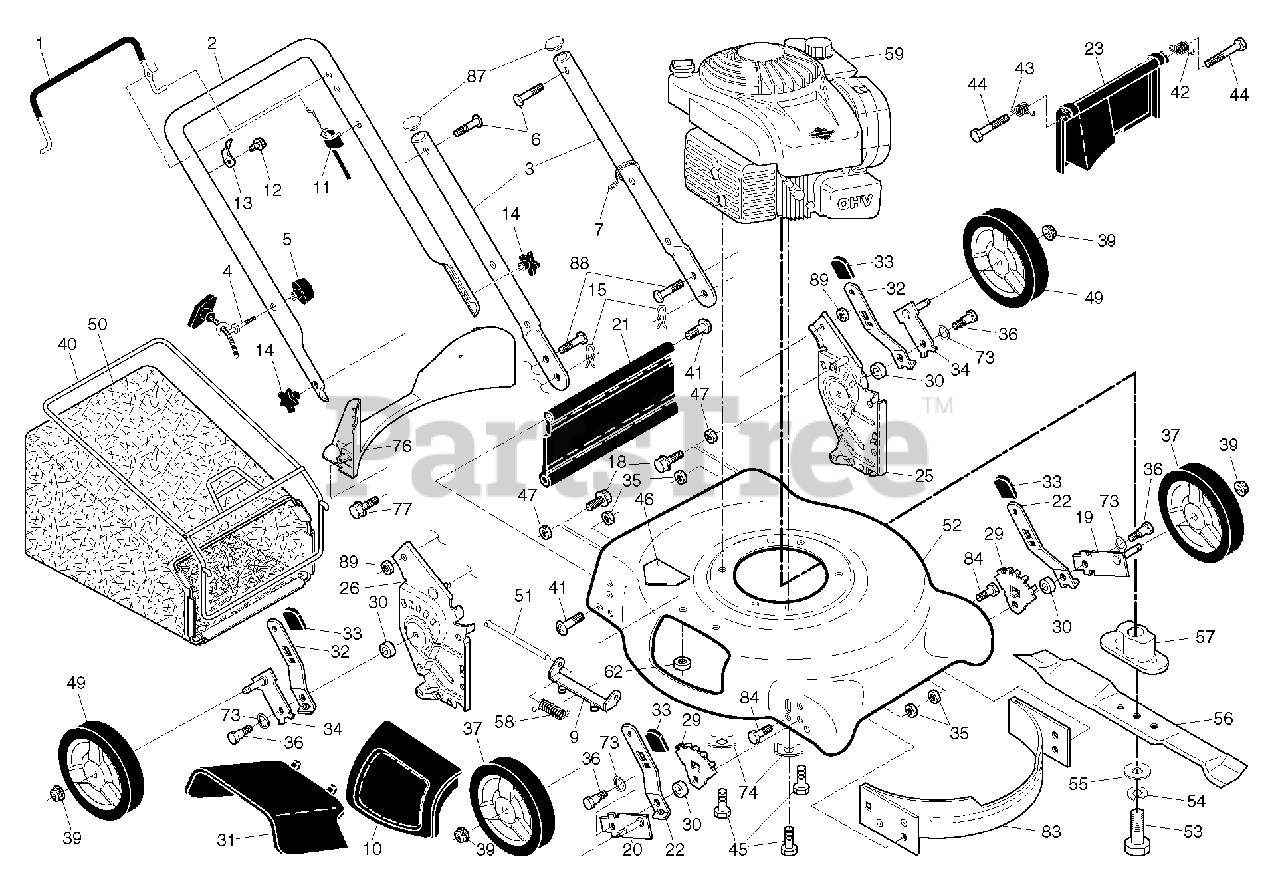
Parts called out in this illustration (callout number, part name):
1	BAIL.ARM.ASSY:STRAIGHT OM
2	HANDLE.UP.DST.SS/VS.FG/RG.NHGY
3	HANDLE.LOWER.DOME.BT.GREY
4	GUIDE.ROPE.BLK.ZINC.CHROM
5	T-KNOB.NEW ROPE GUIDE
6	BOLT, HANDLE 5/16-18X1.75
7	TIE GUIDE
9	BRACKET.ASM.HOUSING.EZ.MUL
10	DOOR.MULCH.21".REAR.PUSH.GRAY
11	CONTROL.ZONE.ASM
13	BRACKET.UPSTOP.RT
14	KNOB.HANDLE.PLASTIC.STAR.BLACK
15	HAIRPIN COTTER
18	SCREW 1/4X20
19	AXLE ARM ASSY FRONT LH
20	AXLE ARM ASSY FRONT RH
21	SKIRT.REAR.21.PUSH
22	SELECTOR SPRING, FRONT
23	DOOR.REAR.21.DOMED.498
25	BRACKET.ASM.HAND.LW.21.LT.GREY
26	BRACKET.ASM.HAND.LW.21.RT.GREY
29	WHEEL ADJ BRACKET FRONT
30	SPACER.HEIGHT.ADJUSTER(2 2)3 2
31	CLIP ON DISCHARGE GUARD
32	SPRING.SELECTOR.21RD.HTTRT.BZP
33	SELECTOR KNOB
34	ARM.ASM.AXLE.REAR.5/9.POS.BZP
35	NUT.FLANGE.HEX.5/16X18.BLACK
36	SHOULDER BOLT 5/16-18
37	WHEEL AND TIRE ASSY, REAR
39	NUT.HEX.FLANGE.3/8-16.LO(3 2)
40	FRAME.BAG.21.REAR.DOMED.PUSH
41	SCREW.1/4-20X21/4.HEX.
42	SPRING.LH.22.REAR.DOOR.EZ.EMPT
43	SPRING.RH.22.REAR.DOOR.EZ.
45	BOLT 3/8-16X1-1/8
46	DANGER DECAL
47	NUT.71038.31-18.HEX.NYLOCK
49	WHEEL AND TIRE ASSY, REAR
50	GBAG.2323029ER.HU.VENT.GRY.SIL
51	ROD.HINGE.COMBI-C
52	HOUSING.21.M/C.DOME.ORANGE
53	SCREW, HEX HD 3/8-24 X 1-3/8
54	LOCKWASHER
55	WASHER,HARDEN
56	BLADE.21.PUSH/RWGD/FWGD
57	ADAPTOR.BLADE.7/8
58	TORSION SPRING
62	LOCKNUT.NYLOC.1/4-20
73	WASHER.CURVED.CYLINDRICAL
74	WASHER.ENGINE.BZP
76	BAFFLE.REAR.PLASTIC.21.RD.ECON
77	SCREW.HX.13X.750
83	BAFFLE.FRONT.21.DOME.US
84	BOLT.5/16HEX.WHS.HD
87	PLUG.PLASTIC.7/8".14-20.GAUGE
88	BOLT.CARRIAGE.LN.5/16-18X.5/8
89	LOCKNUT-FLANGE 5/16-18
